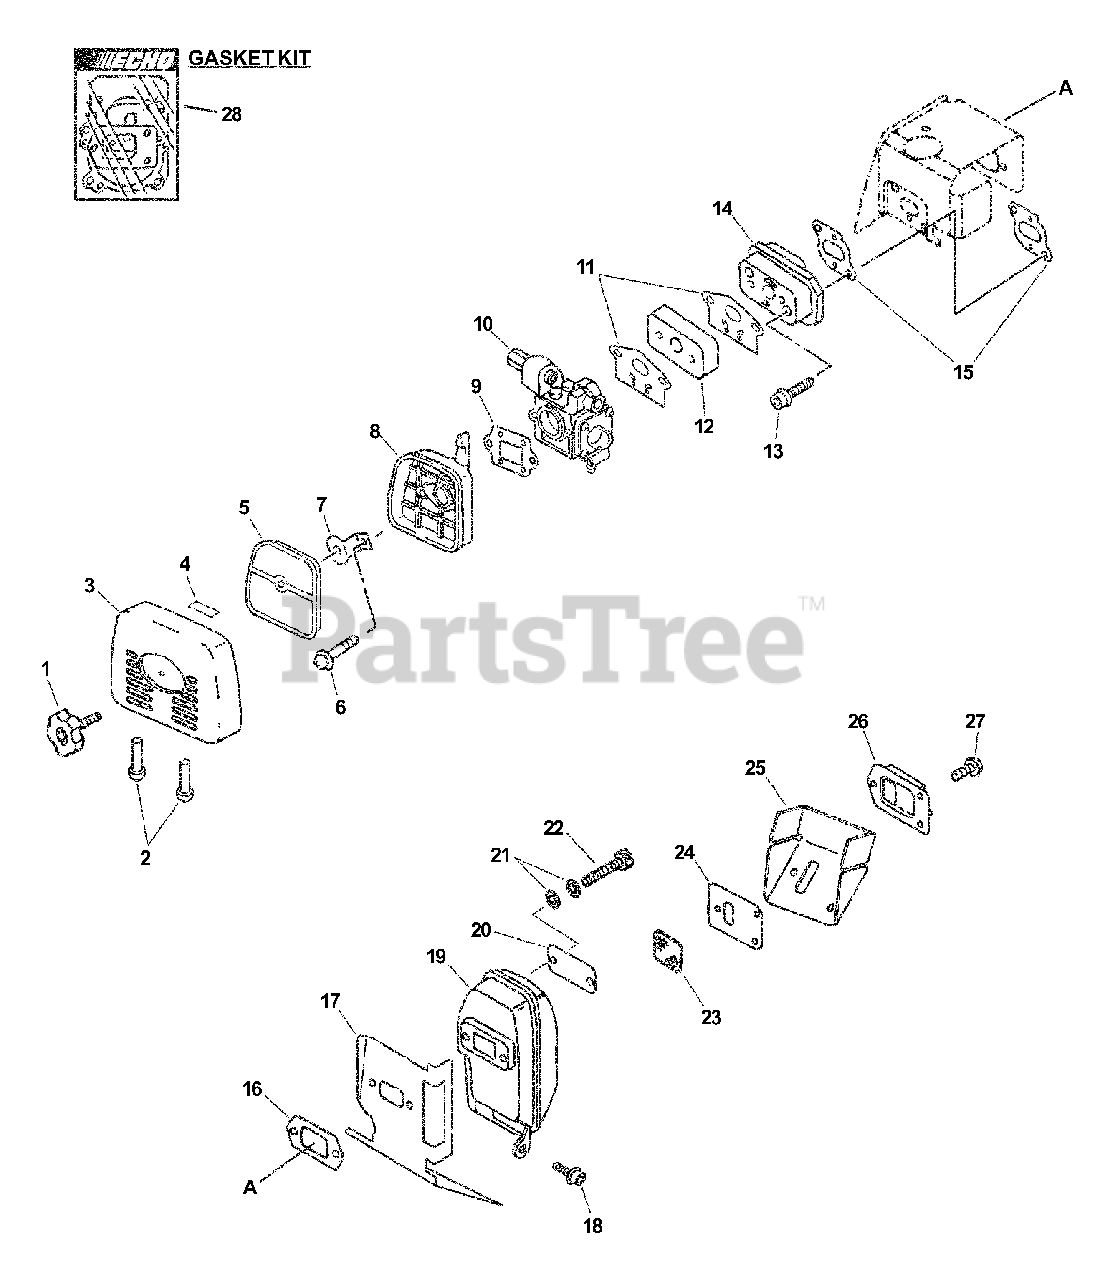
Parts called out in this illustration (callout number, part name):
1	THUMBSCREW
3	COVER, AIR FILTER
4	LABEL, CHOKE
5	FILTER, HEAVY-DUTY AIR
6	SCREW 5×65
7	PLATE, PREVENT
8	CASE, AIR FILTER
10	CARBURETOR - RB-K61A
11	GASKET, CARBURETOR
12	INSULATOR, INTAKE
13	BOLT 5×25
14	INSULATOR, INTAKE
15	GASKET, INTAKE
16	GASKET, EXHAUST
17	SHIELD, EXHAUST
18	BOLT 5×16
19	MUFFLER
20	PLATE, EYE
21	CONICAL WASHER
22	BOLT M5×65
23	SCREEN, SPARK ARRESTER
24	GASKET, EXHAUST
25	GASKET, EXHAUST
26	GUIDE, EXHAUST
27	SCREW 4×12
28	GASKET KIT
